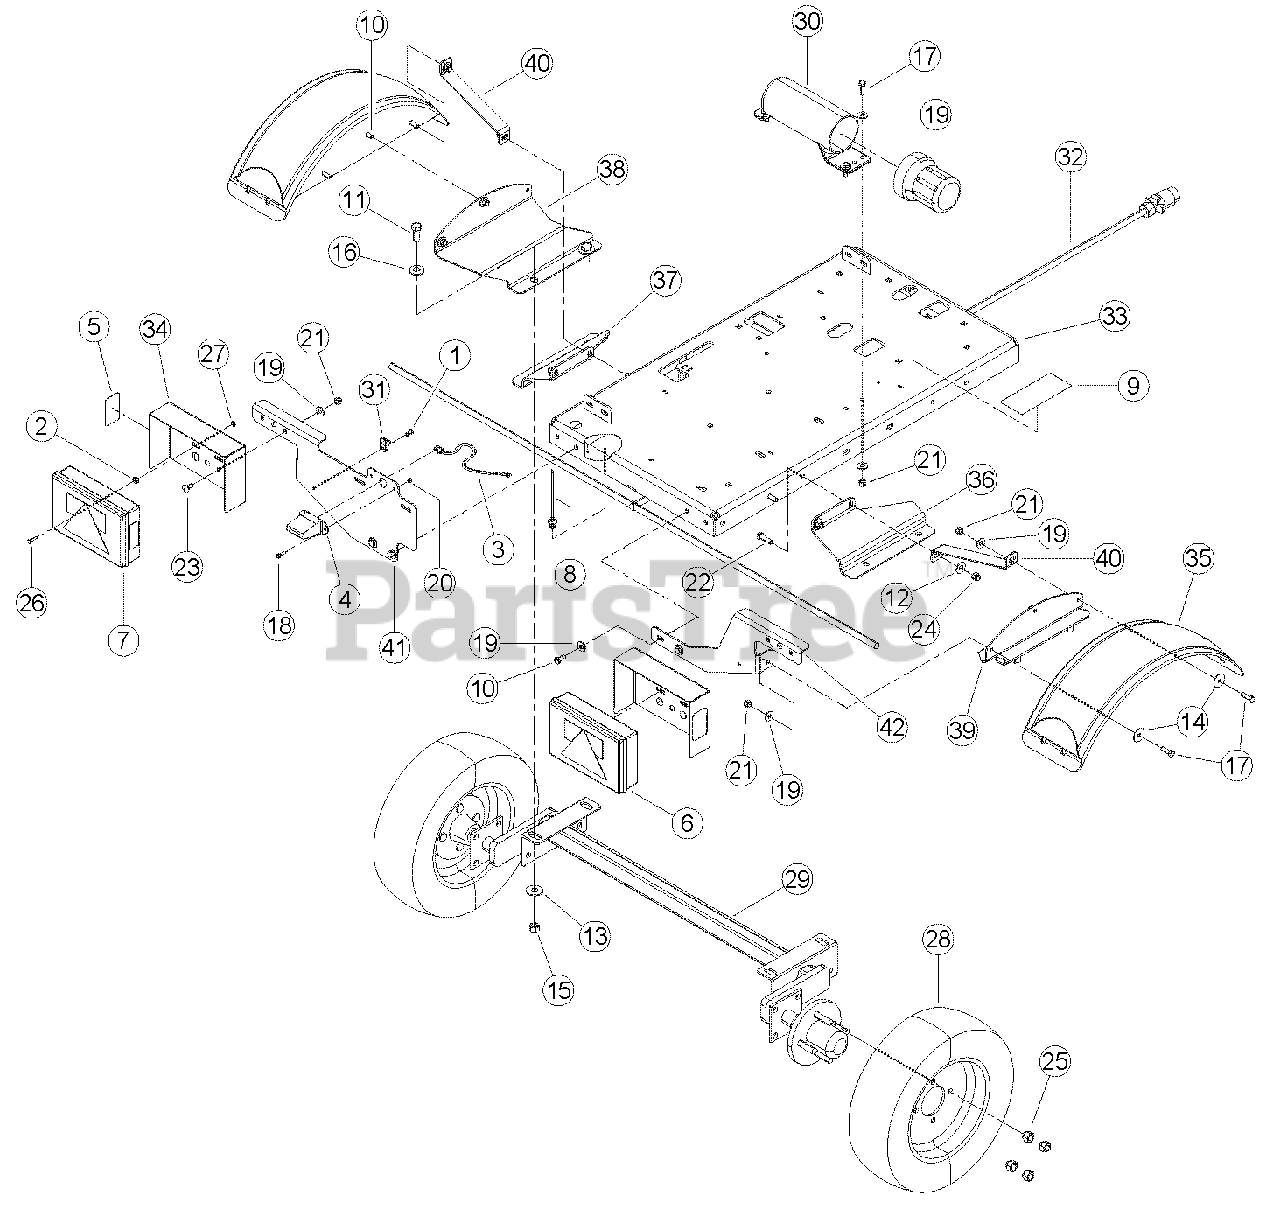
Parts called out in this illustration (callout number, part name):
1	RIVET, 1/4 X 3/4 ST POP
2	GROMMET, 1/4 X 5/8 RUBBER
3	PLUG, 12 VOLT LIGHT
4	LIGHT, LICENSE PLATE
5	REFLECTOR, WIDE ANGLE RED
6	LIGHT, TAIL RH
7	LIGHT, TAIL LH
8	TIE, DOME FIR TREE
9	DECAL, MUTILINGUAL MANUAL
10	BOLT, 5/16 X 3/4 HEX HD GR5 ZP
11	BOLT, 1/2 X 1-1/4 HHCS GR5 NC ZP
12	WASHER, 3/8 FLAT ZP
13	WASHER, 1/2 FLAT ZP
14	WASHER, 5/16 FENDER ZP
15	NUT, 1/2 CENTERLOCK GRB ZP
16	WASHER 1/2 SAE FLAT ZP
17	BOLT, 5/16 X 1 HHCS GR5 NC ZP
18	SCREW, #10 X 3/4 HEX TAP SC
19	WASHER, 5/16 FLAT ZP
20	NUT, 8-32 NYLOCK
21	NUT, 5/16 NE NYLOCK ZP
22	BOLT, 3/8 X 1-1/4 HEX HD GR5 ZP
23	BOLT, 5/16 X 3/4 CRG GR5 NC ZP
24	NUT, 3/8 NE NYLOCK ZP
25	NUT, 1/2-20 WHEEL
26	BOLT, 10-24 X 3/4 HHCS GR8 PLAIN
27	NUT, #10-24 K-LOCK ZP
28	ASSEMBLY, TIRE + WHEEL 4.80-8
29	AXLE, 1000LB TORSION
30	CONTAINER, MANUAL
31	CLAMP, CABLE MOUNT
32	HARNESS, TRAILER LIGHTING
33	WELDMENT, CHIPPER TRAILER
34	BRACKET, LIGHT
35	FENDER, BLACK PLASTIC DRILLED
36	SUPPORT, AXLE FENDER RH (VIN 5VJAA0017AW002656 AND ABOVE)
36	SUPPORT, AXLE FENDER RH (VIN 5VJAA0017AW002655 AND BELOW)
37	SUPPORT, AXLE FENDER LH (VIN 5VJAA0017AW002656 AND ABOVE)
37	SUPPORT AXLE FENDER (VIN 5VJAA0017AW002655 AND BELOW)
38	SHEET, MOUNT FENDER LH (VIN 5VJAA0017AW002656 AND ABOVE)
38	SHEET, MOUNT FENDER LH (VIN 5VJAA0017AW002655 AND BELOW)
39	SHEET, MOUNT FENDER RH (VIN 5VJAA0017AW002656 AND ABOVE)
39	SHEET, MOUNT FENDER RH (VIN 5VJAA0017AW002655 AND BELOW)
40	BRACKET, FENDER SUPPORT (VIN 5VJAA0017AW002656 AND ABOVE)
40	BRACKET, FENDER (VIN 5VJAA0017AW002655 AND BELOW)
41	BRACKET, LIGHT-RH
42	BRACKET, LIGHT-LH
